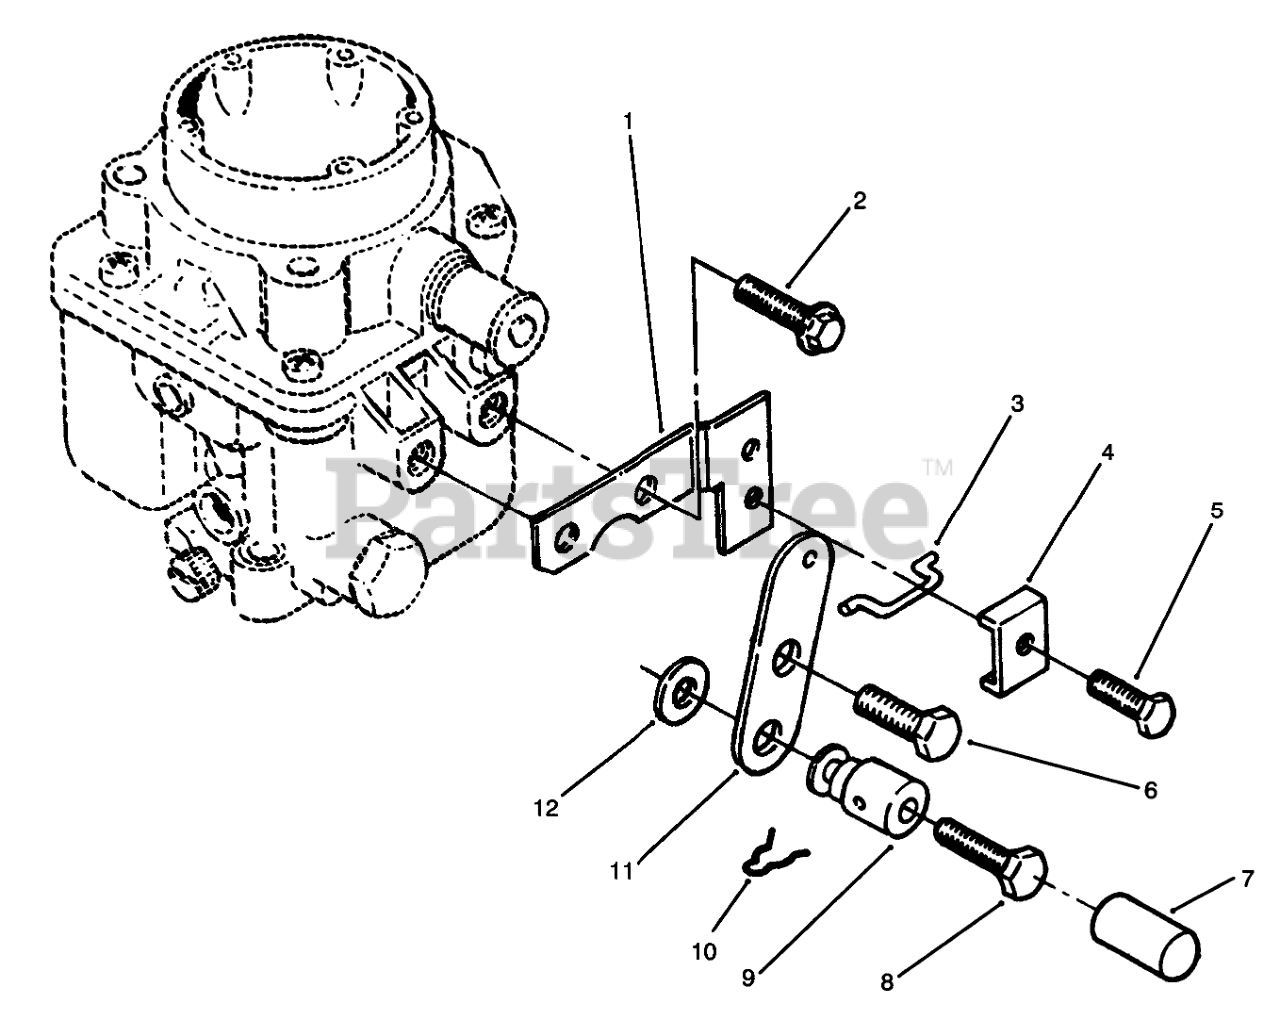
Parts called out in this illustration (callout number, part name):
1	BRACKET
2	SCREW-HWH
3	LINK-CHOKE
5	SCREW-TAPPING
6	MACHINE SCREW
8	SCREW
9	SWIVEL-CHOKE LEVER
10	PIN-COTTER
11	CHOKE-LEVER (PRIMED)
12	Washer
